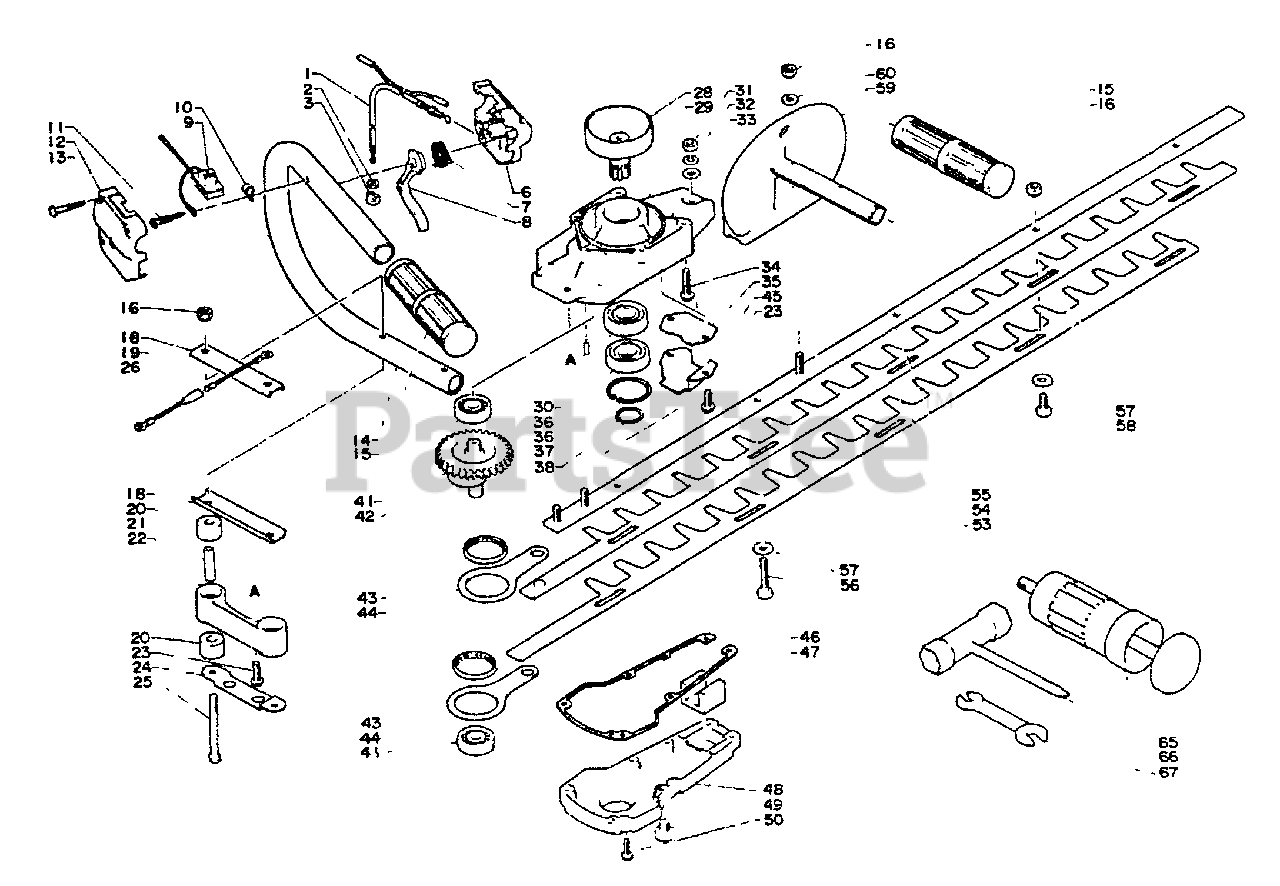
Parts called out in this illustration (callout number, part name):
1	CABLE, THROTTLE
6	BRACKET, THROTTLE CONTROL - RIGHT
7	SPRING, TRIGGER
8	TRIGGER, THROTTLE
9	IGNITION SWITCH ASSY
10	HOLDER
11	SCREW - 4X8
12	BRACKET, THROTTLE CONTROL - LEFT
13	SCREW - 4X25
14	HANDLE - REAR
15	GRIP, HANDLE
16	LOCKNUT - 5
18	BRACKET, HANDLE - LOWER
19	LEAD - GROUND
21	SPACER
22	BRACKET, HANDLE
23	SCREW - 5X14
24	PLATE
25	SCREW - 5X60
26	LEAD - GROUND
28	DRUM, CLUTCH
29	CASE, GEAR
30	PIN - LOCATING
31	LOCKNUT - 6
32	LOCKWASHER - 6
33	WASHER - 6
34	SCREW - 5X20
35	PLATE, GUIDE
36	BEARING, BALL - 6200
37	RING, RETAINING - 32
38	RING, RETAINING - 17
41	BEARING, BALL - 6003
42	GEAR
43	BEARING, NEEDLE
44	ROD, CONNECTING
45	GUIDE
46	GASKET, GEAR CASE
47	SEAL, FELT
48	LID, GEAR CASE
49	BOLT - 8X8
50	SCREW - 4X16
53	TRIMMER BLADE SET
54	TRIMMER BLADE SET
55	SUPPORT, BLADE
56	BOLT
57	WASHER
58	BOLT
59	HANDLE - FRONT
60	WASHER - 5
65	PUMP, GREASE
66	T-WRENCH
67	SPANNER - 8X10mm
